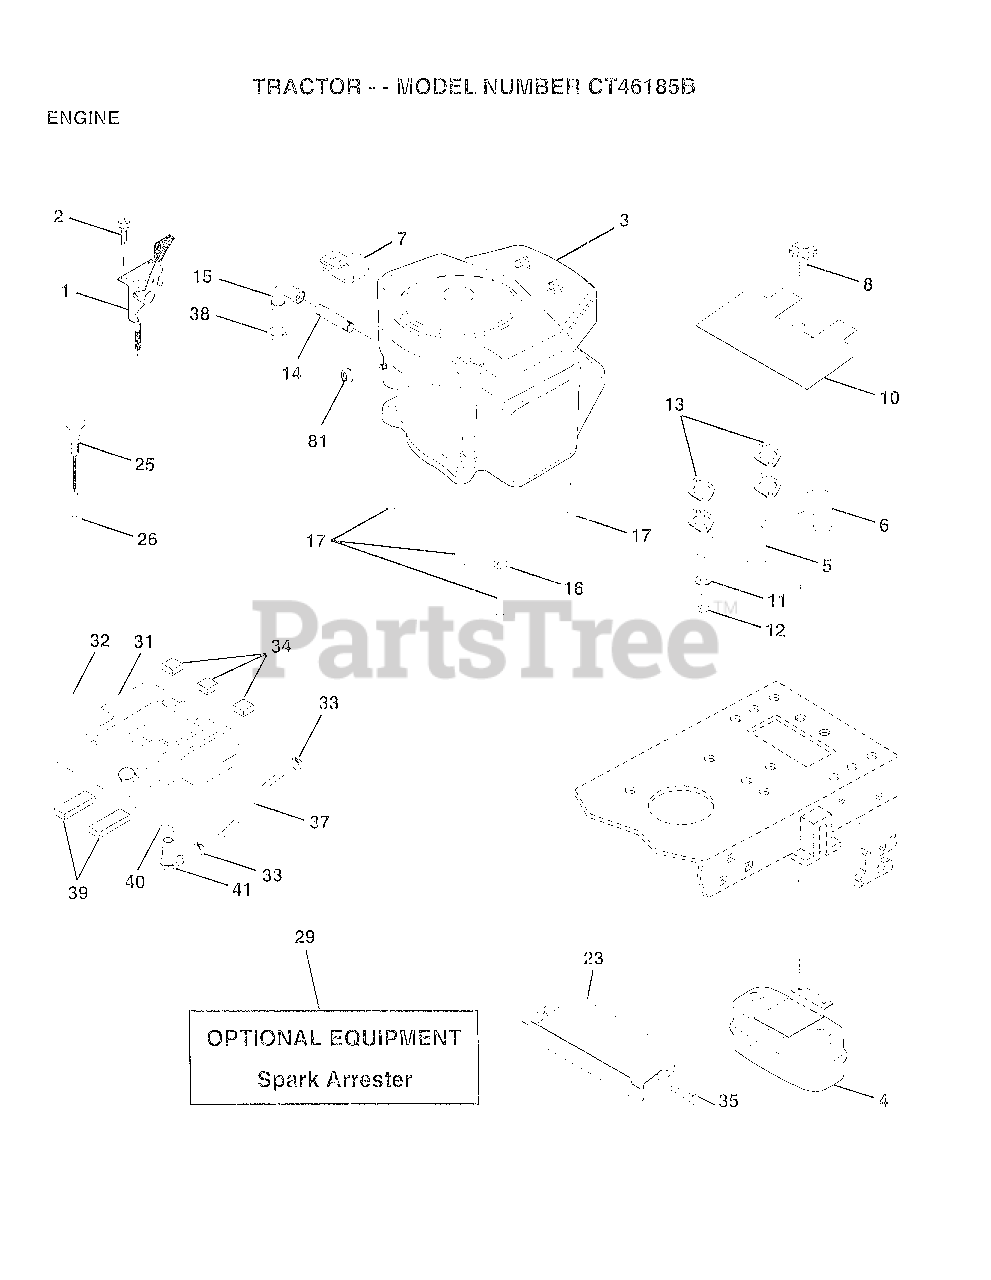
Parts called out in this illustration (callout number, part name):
1	CONTROL.TRTL.37
2	SCREW LT
4	MUFFLER.TW.LOTONE
5	EXHAUST.B&S.18.LH
6	EXHAUST.B&S.18.RH
7	CLAMP.TUBE.DBL.EN
8	BOLT.5/16-18.UNC
10	SHIELD.HEAT.
11	LOCKWASHER
13	GASKET MUFFLER
14	PIPE NIPPLE LT
15	ELBOW
16	LOCKWASHER
17	SCREW LT
23	SHIELD.BRN/DBR.GD
25	"CONTROL.CHOKE.51"""
26	"NUT,KEPS 3/8-24IM"
27	"SCREW-TT,10-32 FL"
31	TANK FUEL REAR
32	CAP ASM FUEL
33	HOSE CLAMP
34	PAD-SPACER LT
35	SCREW
37	FUEL LINE T
39	PAD IDLER TI
40	BUSHING OUTLET T
41	STEM.TANK.FUEL
81	NUT
